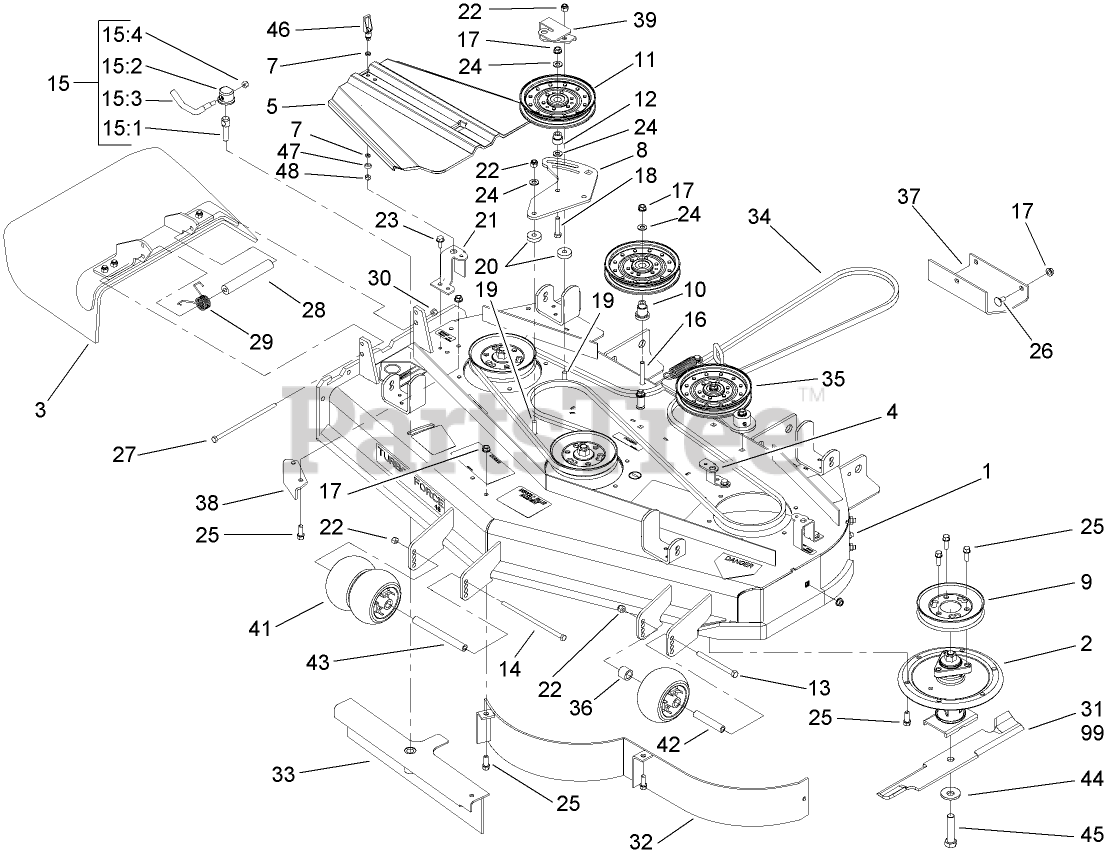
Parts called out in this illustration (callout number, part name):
1	DECK DECAL ASM
2	SPINDLE ASM
3	RUBBER DEFLECTOR ASM
4	BRACKET-COVER, TALL
5	COVER-BELT
7	WASHER
8	PLATE-IDLER
9	PULLEY
10	MOUNT-PULLEY
11	Idler-Flat
12	BUSHING-IDLER
13	SCREW-HH
14	SCREW-HH
15	LEVER ASM
15:1	Screw-Lock
15:2	CAP-LOCK
15:3	Lever-Lock
15:4	NUT-LOCK, NI
16	SCREW-CARR
17	NUT-HHF, WHIZ
18	SCREW-HH
19	SCREW-CARR
20	Spacer
21	BRACKET-COVER
22	NUT-LOCK, NI
23	SCREW-HWHTF
24	WASHER-FLAT
25	SCREW-HWH
26	SCREW-CARR
27	SCREW-HH
28	SPACER
29	SPRING-TORSION
30	NUT-LOCK, NI
31	BLADE-16.5 INCH (HIGH FLOW)
32	BAFFLE ASM
33	BAFFLE
34	BELT-V
35	SPRING IDLER ASM
36	TUBE-SPACER
38	BAFFLE-DISCHARGE
39	BRACKET-COVER
41	ROLLER-SCALP, ANTI
42	TUBE-SPANNER
43	SPACER-WHEEL
44	Washer-Blade Bolt, Heavy
45	Screw-Cap
46	HANDLE-LATCH, SWELL
47	BUSHING-LATCH, SWELL
48	NUT-LOCK, HH
99	BLADE-RECYCLER, 16.5 INCH
99	BLADE-ROTARY, 16.5 INCH (ATOMIC)
99	BLADE-ROTARY, 16.5 INCH (MED FLOW)
99	BLADE-ROTARY, 16.5 INCH (LOW FLOW)
